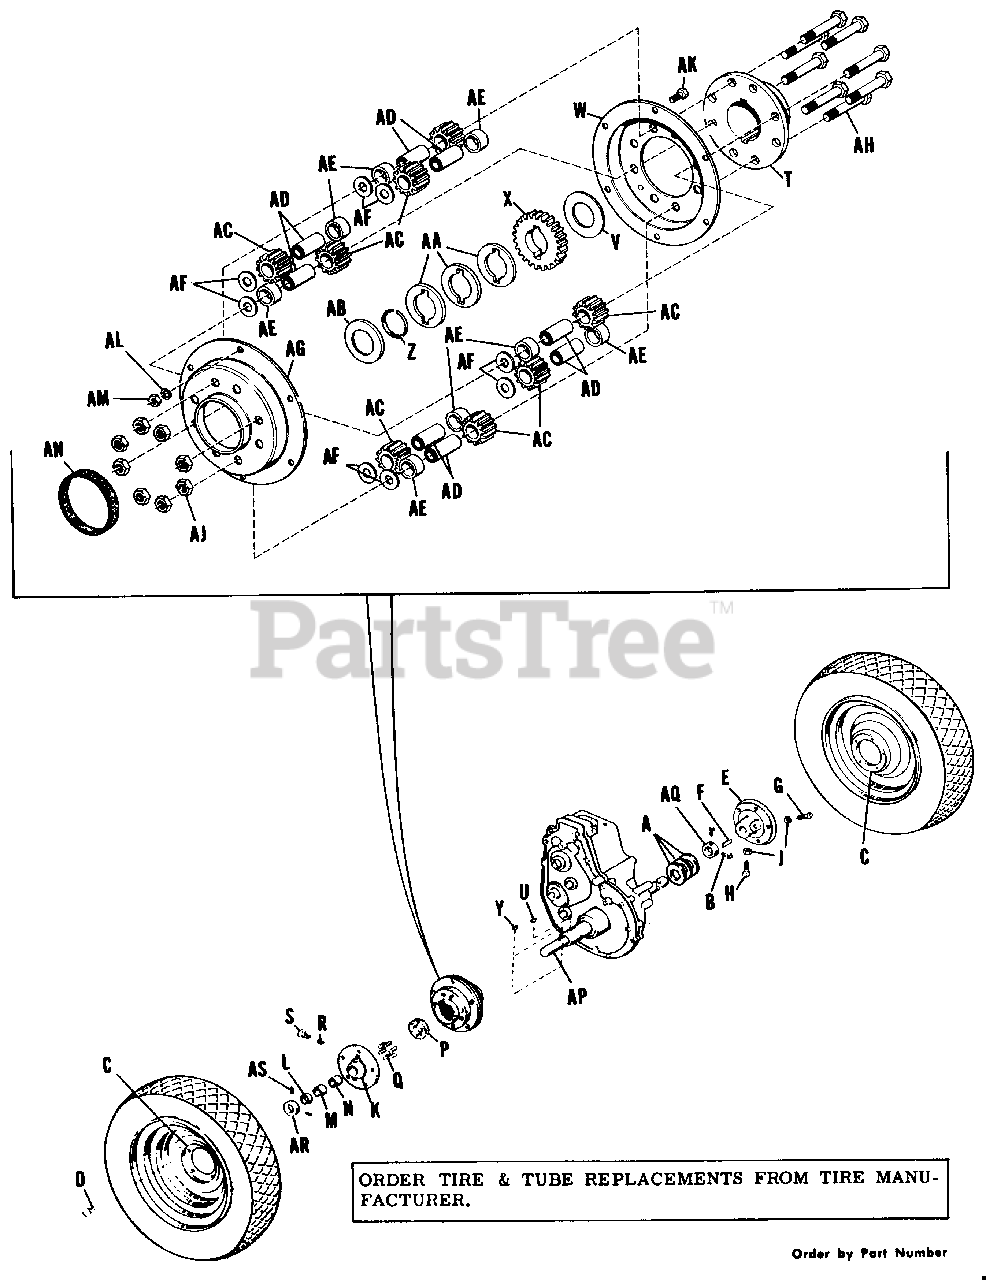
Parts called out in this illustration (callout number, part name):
B	Screw, Set, Cup Pt. Sq. Hd., 5/16"-18 NC x 1/2" lg.
E	Hub, Wheel, L.H.
G	Screw, Set Sq. Hd., Cone, 3/8"-16 N.C. x 1-1/2" lg.
H	Screw, Set, Sq. Hd., Cup, 3/8"-16 N.C. x 1" lg.
J	Nut, Hex., Jam, 3/8"-16 N.C.
K	Hub, Wheel, R.H.
M	Bearing, Nylon
P	Gear, Differential
Q	Pin, Roll
T	Carrier, Differential
V	Washer, Axle
W	Cover, Differential
X	Gear, Differential
Y	Key, Hi-Pro
Z	Ring, Retaining
AA	Washer, Axle
AB	Washer, Axle
AC	Pinion, Differential
AD	Spindle, Pinion Differential
AE	Spacer, Differential
AF	Washer, Plain
AG	Cover, Differential
AH	Screw, Cap, Hex., 3/8"-16 N.C. x 2-1/4" lg.
AJ	Nut, Lock, Full Hex., 3/8"-16 N.C.
AK	Screw, Cap, Hex., 1/4"-20 N.C. x 1/2" lg.
AL	Washer, Lock, 1/4"
AM	Nut, Full, Hex., 1/4"-20 N.C.
AN	Seal, Differential Cover
AP	Axle, Rear
AQ	Collar, Axle
AR	Collar, Axle
AS	Screw, Set, Cup Point, Hollow Head, 5/16"-18 N.C. x 5/16" lg
